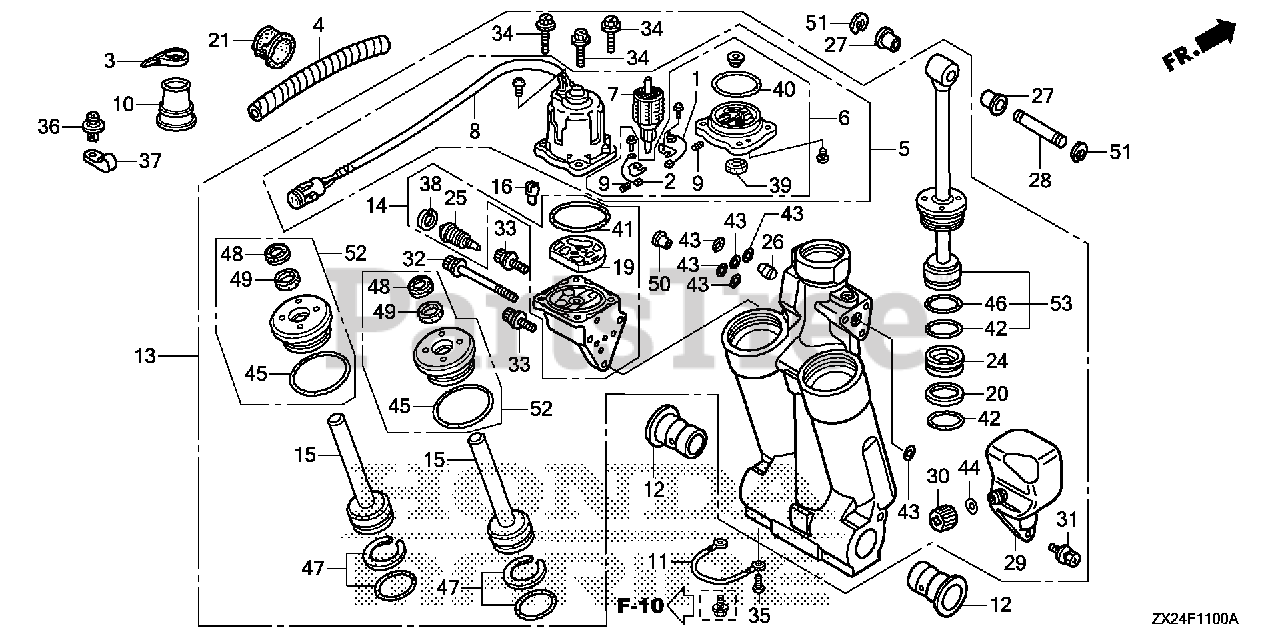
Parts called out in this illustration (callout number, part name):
1	BREAKER ASSY.
2	BRUSH ASSY.
3	BAND (BLACK 3.5X140)
4	TUBE, SPIRAL (12X14.6)
5	MOTOR ASSY., POWER TILT
6	BRACKET ASSY.
9	SPRING, MOTOR
10	GROMMET, CASE (LOWER) (C)
11	WIRE, LEAD (1.5X116MM)
12	BUSH, SWIVEL CASE
13	TRIM-TILT ASSY., POWER
15	ROD, PISTON (B)
18	GUIDE, ROD
20	RING, BACK-UP
21	BUSH, MOTOR CODE
22	ROD, PISTON
25	VALVE, MANUAL
26	VALVE, RESERVOIR
27	BUSH, CYLINDER (LOWER)
28	PIN, CYLINDER (UPPER)
29	TANK, OIL
30	CAP, OIL TANK
31	BOLT, RECESSED
34	BOLT, HEX.
35	SCREW, PAN (6X8)
36	SCREW, RIVET (5X10)
37	CLIP (10.7MM)
38	CIRCLIP (INNER)
40	O-RING (2.0X70.5)
41	O-RING (1.8X69.6)
42	O-RING (3.5X38.7)
43	O-RING (1.8X7.7)
44	O-RING (1.9X11)
45	O-RING (3.5X35.7)
46	O-RING (3.5X41.7)
47	O-RING SET (3.5X31.7)
48	SEAL, WATER
51	E-RING (15MM)
52	GUIDE, ROD
53	ROD, PISTON
